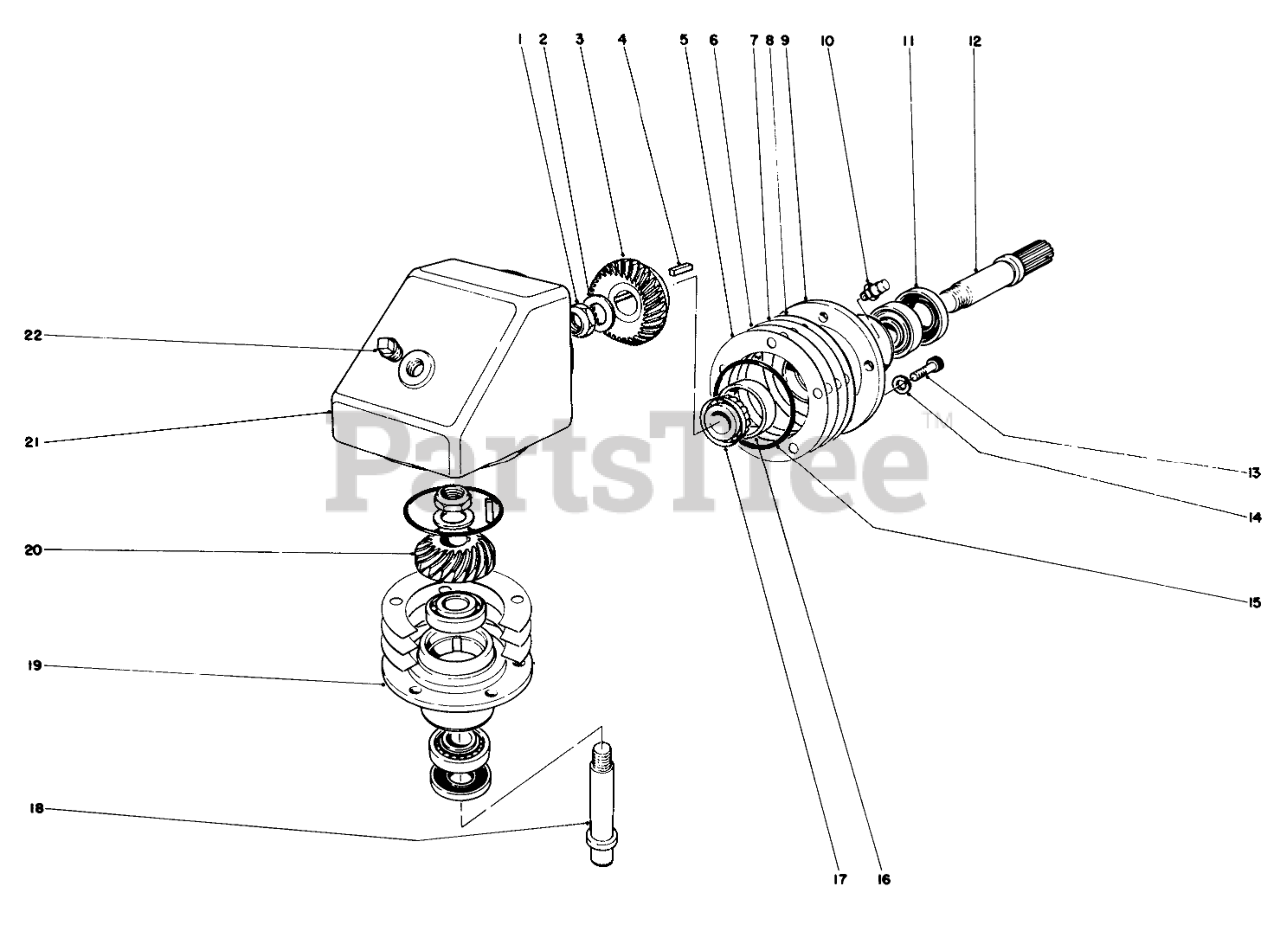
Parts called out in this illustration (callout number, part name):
1	NUT-LOCK, NI
2	THRUST WASHER
4	KEY-SQUARE
5	.002 SHIM (RED)
6	.005 SHIM (BLUE)
7	.015 SHIM (PINK)
9	INPUT BRG HSG
11	OIL SEAL
12	INPUT SHAFT
13	SCREW-HSH
14	WASHER-LOCK
15	O-RING
16	BEARING-CUP
17	CONE-BEARING
18	OUTPUT SHAFT
19	OUTPUT BRG HSG
20	PINION
21	GEAR BOX
22	3/8-18 SQ HD PLUG/MAG
